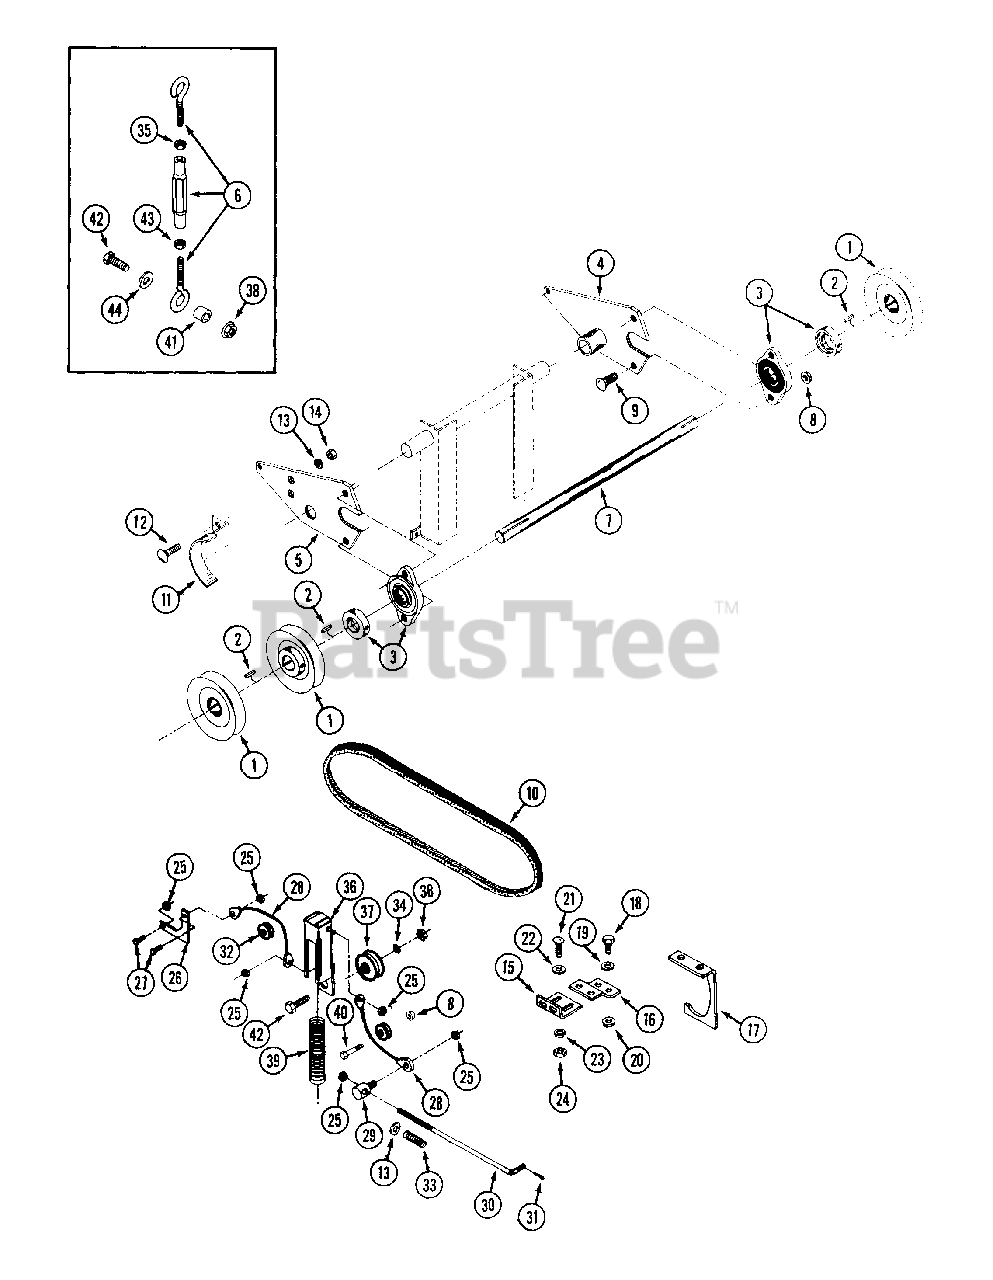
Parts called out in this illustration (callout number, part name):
1	PULLEY - 4" OD x 3/4" ID
2	KEY - 3/16" x 3/16" x 1"
3	BEARING - flanged
4	MOUNT - bearing L.H.
5	MOUNT - bearing R.H.
7	SHAFT - cross
8	NUT - 5/16 - 18 flange lock
9	BOLT - 5/16" - 18 x 1" carriage
10	BELT - drive 36"
11	RETAINER - cross shaft belt
12	BOLT - 1/4" - 20 x 3/4" carriage
13	LOCKWASHER - 1/4"
14	NUT - 1/4" - 20
15	BRACKET - engine belt retainer
16	BRACKET - engine belt
17	RETAINER - engine belt
18	BOLT - 1/4" - 20 x 3/4"
19	WASHER - 1/4"
20	NUT - 1/4" - 20 flange lock
21	BOLT - 5/16" - 20 x 1" carriage
22	WASHER - 3/8"
23	LOCKWASHER - 5/16"
24	NUT - 5/16" - 18
25	NUT - nylock 1/4" - 20
26	BRACKET - "L", brake linkage
27	BOLT - 1/4" - 20 x 1"
28	CABLE - clutch, brake
29	COLLAR - caliper rod
31	PIN - cotter - 3/32" x 1"
32	PULLEY - 1-1/2" OD
33	SPRING - caliper rod
34	LOCKWASHER - 3/8"
35	NUT - 3/8" - 16
36	TUBE - drive idler
37	PULLEY - idler 2-1/4" O.D.
38	NUT - 3/8" - 16 flange lock
39	SPRING - belt tightener
40	BOLT - 5/16" - 18 x 2-1/4"
42	BOLT - 3/8" - 16 x 1-1/2"
43	NUT - 3/8" - 16 L.H. threads
